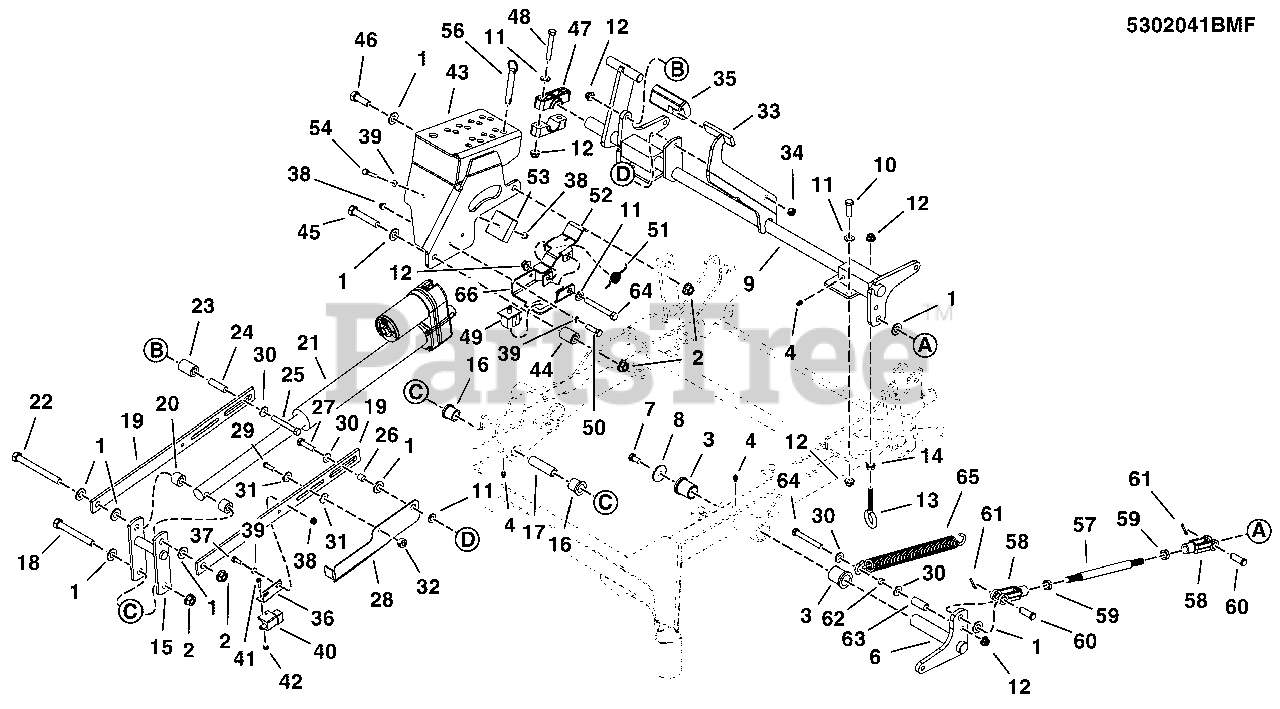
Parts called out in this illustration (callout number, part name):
1	WASHER, 1/2 SAE
2	NUT, 1/2-13 HEX NYLOCK FLANGE
3	BUSHING, FLANGE
4	GREASE FITTING, 1/4-28 STRAIGHT
6	WELD., DECK LIFT LEVER - LH - RED
7	BOLT, 3/8-16 X 3/4, GD5, YZ WITH PATCH
8	WASHER, .390 X 1.50 X .109, YZ
9	WELD, DECK LIFT SHAFT - OUTFRONT - RED
10	BOLT, 3/8-16 X 1-1/4 GD5
11	WASHER, 3/8 SAE
12	NUT, 3/8-16 HEX NYLOCK FLANGE
13	EYE BOLT, 3/8-16 X 4, 2 1/8 OF THREAD
14	NUT, 3/8-16 HEX SERRATED FLANGE
15	WELD, PIVOT LINK - ACTUATOR - RED
16	BUSHING, FLANGED, 3/4 X 1 X 1
17	SPACER, .51 X .75 X 2.66
18	BOLT, 1/2-13 X 4 GD5 YZ
19	BAR, ACTUATOR LINK - RED
20	SPACER, .52 X 1.00 X .75, CZ
21	ACTUATOR, 12" STROKE, 1600 LBS
22	BOLT-1/2-13 X 5 GD5 YZ
23	SPACER, .51 X 1.00 X 1.47 CZ
24	SPACER, .38 X .50 X 1.78
25	BOLT, 3/8-16 X 2-3/4 GD5 YZ
26	SPACER, .38 X .50 X .50
27	BOLT, 3/8-16 X 1-1/2 GD5 YZ
28	PLATE, SWITCH COVER - RED
29	PIN-CLEVIS, 5/16 X 1 YZ
30	WASHER, 5/16 USS
31	WASHER, 5/16 SAE
32	COLLAR, 5/16 SET
33	WELD, DECK LIFT PEDAL - RED
34	NUT, 3/8-16 HEX SIDE LOCK
35	RUBBER, FOOT PEDAL
36	PLATE, SWITCH MOUNT - RED
37	BOLT, 1/4-20 X 3/4 GD5 YZ
38	NUT, 1/4-20 HEX NYLOCK FLANGE
39	WASHER, 1/4 SAE
40	SWITCH, PLUNGER, N.O./N.C.
41	SCREW, #10-24 X 3/4 ROUND PHILLIPS
42	NUT, #10-24 HEX NYLON LOCK
43	WELD, CUT HEIGHT BOX - RED
44	SPACER, .52 X 1.00 X 1.38 CZ
45	BOLT, 1/2-13 X 2-3/4 GD5 YZ
46	BOLT, 1/2-13 X 1-1/2 GD5 YZ
47	PIVOT BLOCK, PLASTIC
48	BOLT, 3/8-16 X 2-1/2 GD5 YZ
49	SWITCH, LOWER PRO, NC/NC
50	BOLT, 1/4-20 X 1", GD
51	SPRING, TORSION, .591ID X .40LG X .95WR
52	INDICATOR, DECK POSITION - BLK
53	FLASHER, 90 FPM, OUT FRONT MOWER
54	BOLT, 1/4-20 X 1-1/2, GD5
56	PIN-COTTERLESS
57	ROD, DECK LIFT, OUTFRONT
58	CLEVIS, 1/2-20, STEEL, CLEAR ZINC
59	NUT, 1/2-20 HEX JAM
60	CLEVIS PIN, 1/2 X 1.36 SAE STANDARD
61	PIN, COTTER, 3/32X.75
62	SPACER, .38 X .50 X .27, CZ
63	SPACER, .39 X .63 X 1.50, CZ
64	BOLT, 3/8-16 X 3 GD5 YZ
65	SPRING-EXT, 1.00 ODX13.25LGX.177WR, BLK
66	WELD, SWITCH MOUNT - BLK
